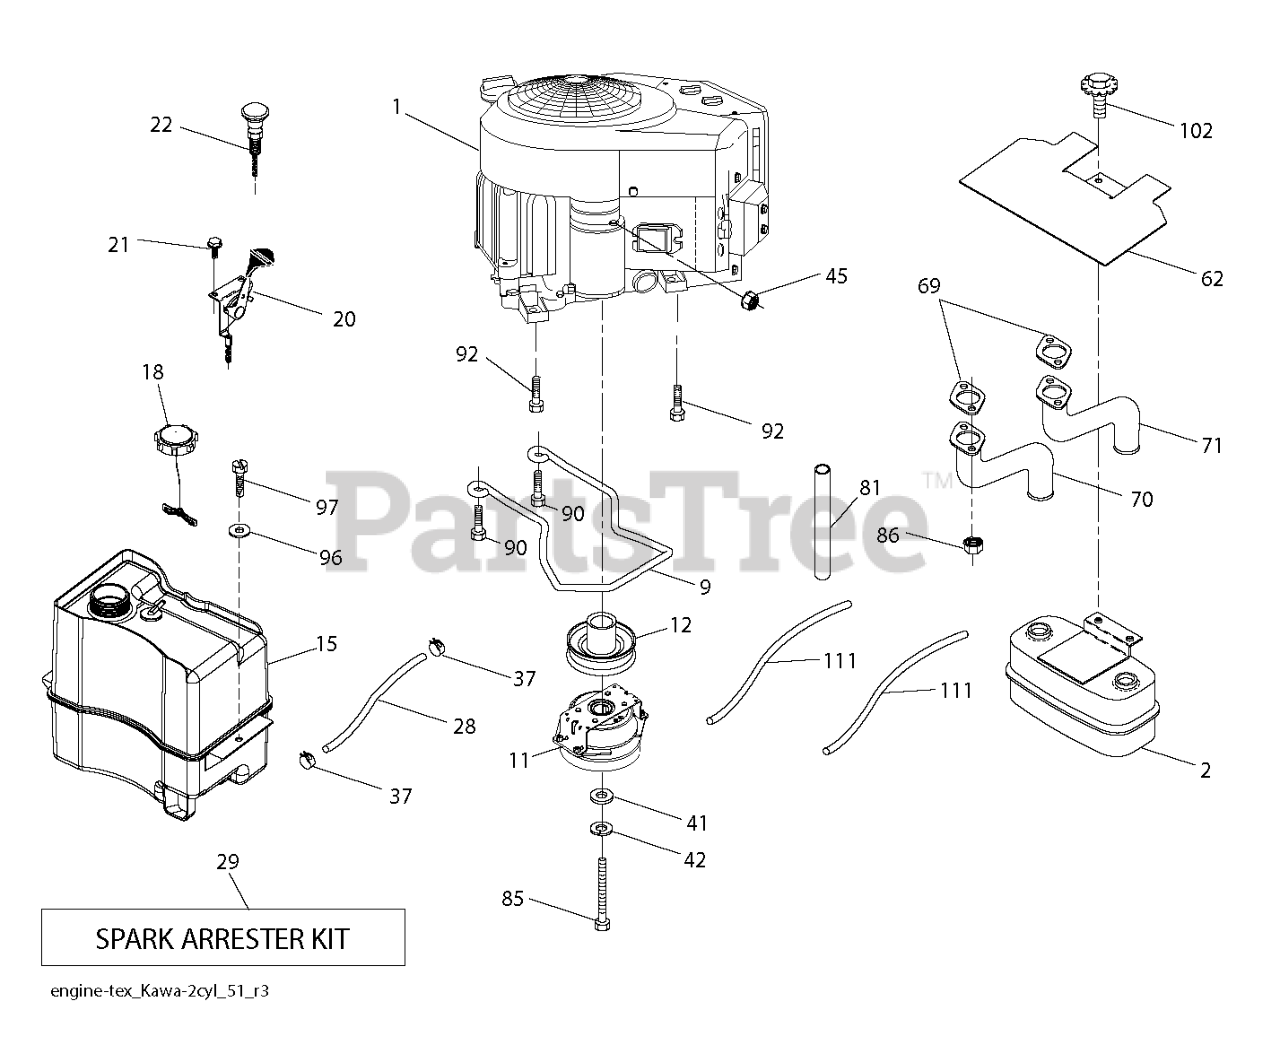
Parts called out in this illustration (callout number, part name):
2	MUFFLER.ASM.TWIN.MNTG.BRACKET
9	KEEPER.BELT.ENG.4.25"2.BLT.431
11	CLUTCH.OGURA.5.0PD.GT1.5A-EH07
12	PULLEY.ENGINE.TUFFTORQ
15	TANK.ASM.FT.2.5GAL.W/CAP.EPA17
18	FUEL.CAP.ASM.2.25TETHRED.RATCH
20	CONTROL.THROTTLE.COBRA.BLACK
21	SCREW.#10 X 0.750.BOS
22	CONTROL, CHOKE
28	LINE.FUEL.64"REAR.EMIS
29	KIT.SPARK ARRESTOR 794945 B&S
37	HOSE CLAMP
42	WASHER 7/16 LOCK
45	NUT
62	SHIELD.HEAT.MUFFLER
69	GASKET.EXHAUST.KOHLER
70	TUBE.EXHAUST.RH.FR961/FR730
71	TUBE.EXHAUST.LH.FR961/FR730
81	TUBE, DRAIN OIL ASM.
85	BOLT.HEX.7/16-20X3.75.GR5.RED
86	BLADE ADAPTER
90	SCREW 3/8-16X1
92	SCREW 3/8-16X1
97	SCREW HEXWSHR 1/4-20X3/4
102	SCREW
111	RP PURGE LINE
